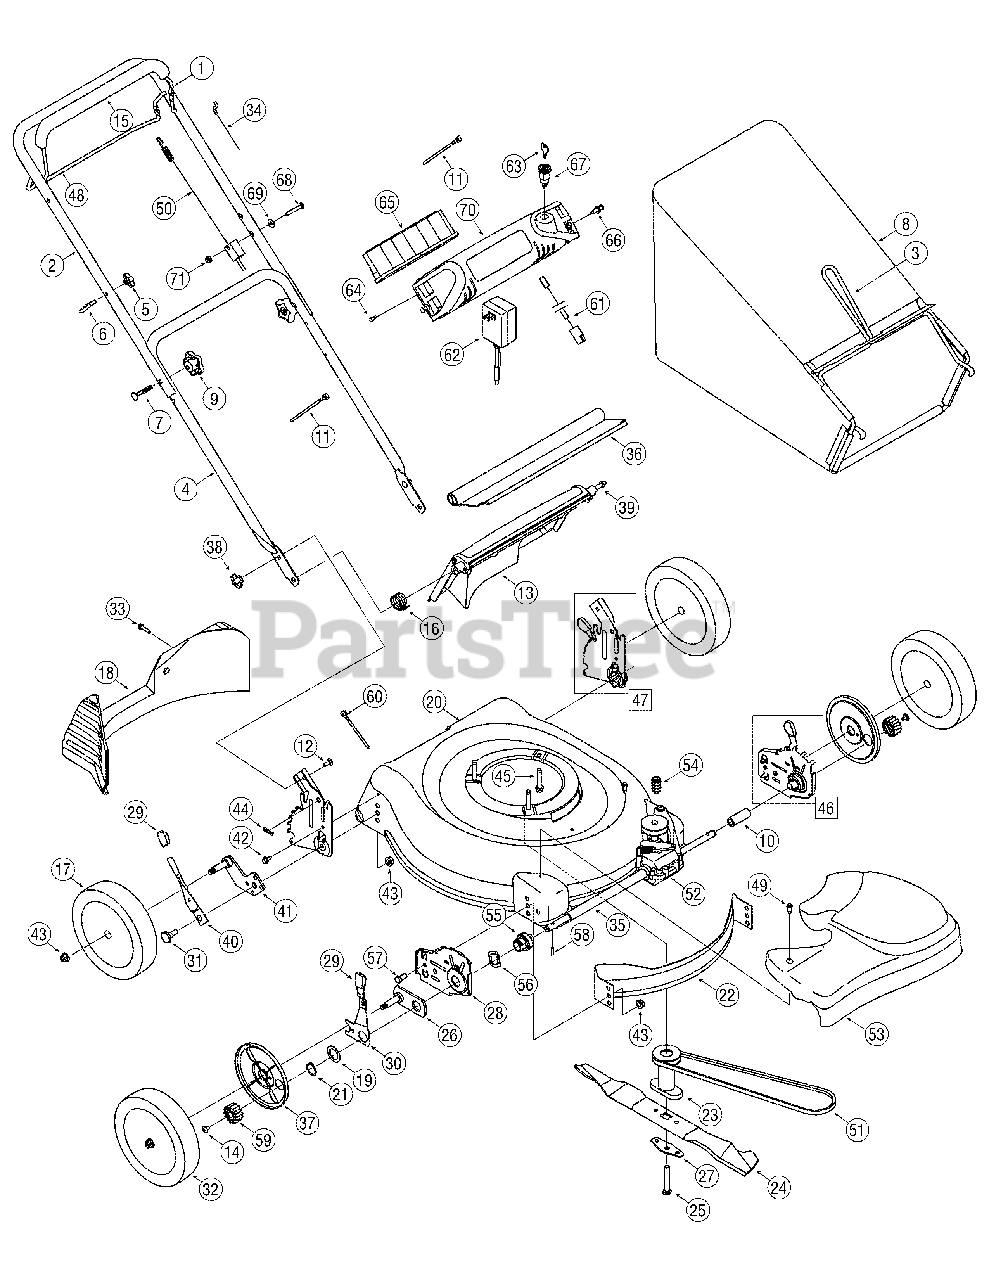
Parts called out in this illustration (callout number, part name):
6	Rope Guide
7	Carriage Bolt ,5/16-18 x 2
8	Grass Bag Assembly
9	Hand Knob
10	Sleeve Spacer - LH
11	Cable Tie
12	Carriage Bolt ,1/4-20
13	Rear Discharge Door
14	Screw 1/4-20
15	Bail Cover
16	Torsion Spring - RH
17	Rear Wheel, 8" x 2.125"
18	Rear Baffle
19	Washer, 1.5" OD
21	Snap Ring
22	Front Baffle
23	Blade Adapter w/Pulley
24	21" Standard Cut Blade
25	Hex Bolt , 3/8-24 x 2.5
26	Pivot Plate Assembly
27	Blade Bell Support
28	Height Adjustment Plate - RH
28	Height Adjustment Plate - LH
29	Adjustment Lever Knob
30	Front Lever - RH
30	Front Lever - LH
31	Shoulder Screw
32	Front Wheel, 8" x 2.125"
33	Screw, 1/4-15 x 1.000
34	Control Cable - 40.75"
35	Sleeve Spacer - RH
36	Trailshield
37	Wheel Dust Cap
38	Wing Nut, 1/4-20
39	Rear Door Pivot Rod
40	Spring Lever
41	Pivot Arm Assembly - RH
41	Pivot Arm Assembly - LH
43	Flange Lock Nut, 3/8-16
44	Hairpin Clip
45	TT Sems Screw, 3/8-16 x 1.00
46	Ht. Adj. Assy. Front - LH
46	Ht. Adj. Assy. Front - RH
47	Rear Handle Bracket Assy. - LH
47	Rear Handle Bracket Assy. - RH
48	Drive Control
49	Shoulder Screw
50	Drive Cable
51	V-Belt
52	Transmission Assembly
53	Front Drive Cover
54	Belt Tension Spring
55	Bearing Assembly
56	Wave Washer
57	Hex Screw
58	Dowel Pin
59	Gear, 14T - RH
59	Gear, 14T - LH
60	Cable Tie
61	Electric Starter Harness Assembly
62	Battery Charger 12V
63	Key
64	Screw, #10-16 x .75
65	12 Volt Battery
66	Plastic Rivet
67	Key Switch
68	Screw, 1/4-20 x 1.75
69	Bell Washer
70	Electric Start Battery Housing
71	Flange Lock Nut 1/4-20
